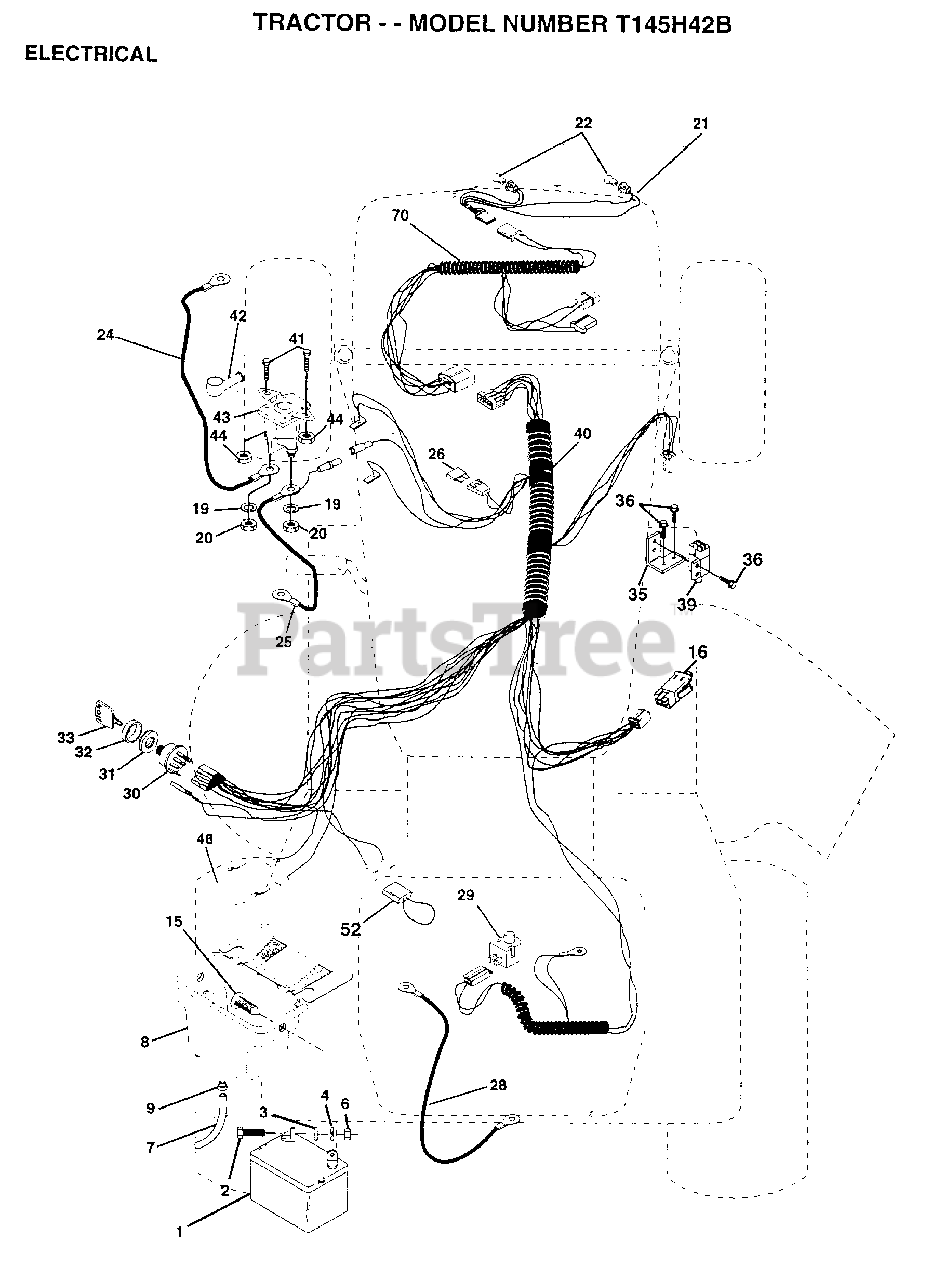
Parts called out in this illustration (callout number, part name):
2	BOLT LT
3	WASHER
4	LOCKWASHER
7	TUBE T
9	HOSE CLAMP T
15	FASTNER.SNAP-IN
16	SWITCH INTERLOCK
20	NUT
21	"HARNESS,LIGHT SOC"
22	HEADLAMP BULB
24	"CABLE T, BATTERY"
25	CABLE.BTRY.6GA.RD
26	FUSE HYT
28	CABLE T
29	SWITCH SEAT
30	SWITCH IGN 4POS
31	NUT IGNITION
32	COVER KEY SWITCH
33	KEY
35	BRACKET LT
36	SCREW
39	SWITCH INTERLOCKT
40	HARNESS.IGNITION
41	BOLT HXHD FIN
44	NUT HXKEP 1/4X20
45	ADAPTER AMMETER
52	PROTECTION LOOP
70	HARNESS ENGINE
